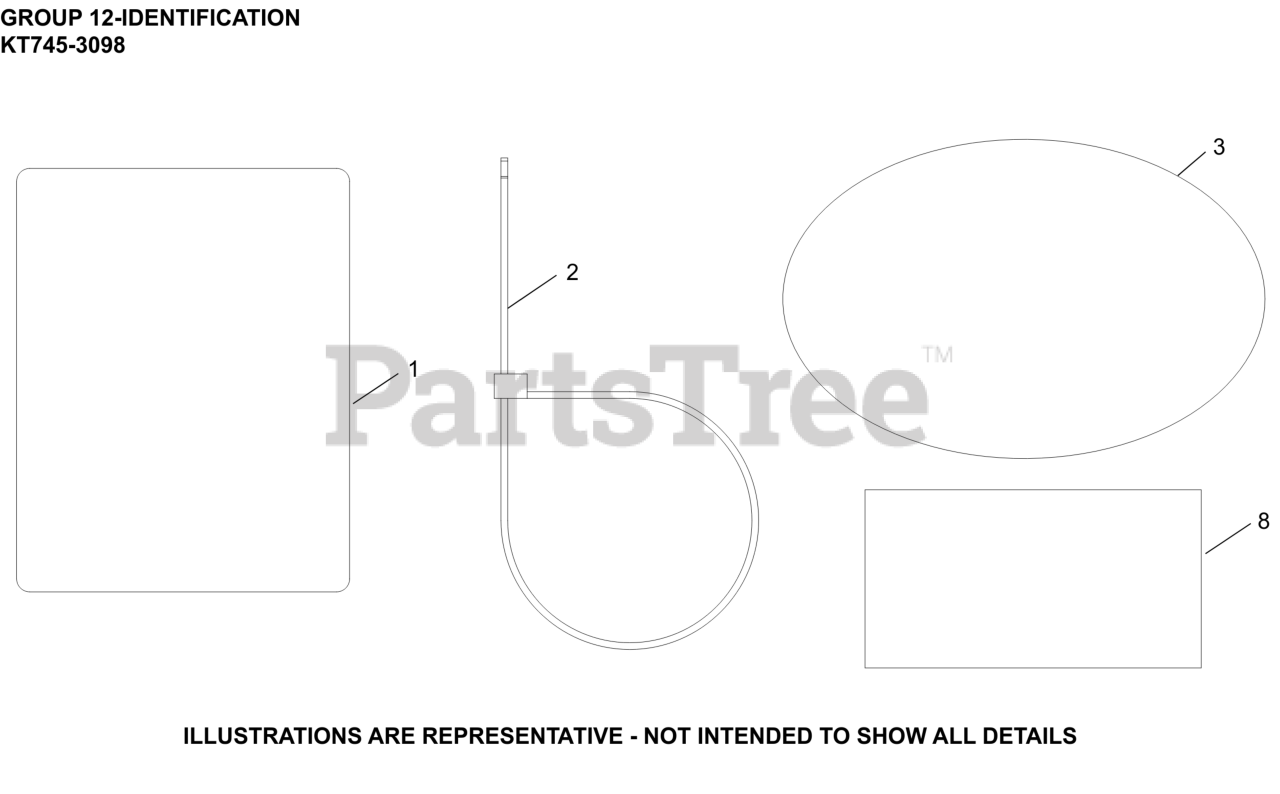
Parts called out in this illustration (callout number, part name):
1	LABEL, CLEAR LAMINATION
3	LABEL, 7000 SERIES (26HP, PRO)
3	LABEL, PRO PERFORMANCE FILTRATION SYSTEM
8	DECAL, USA
